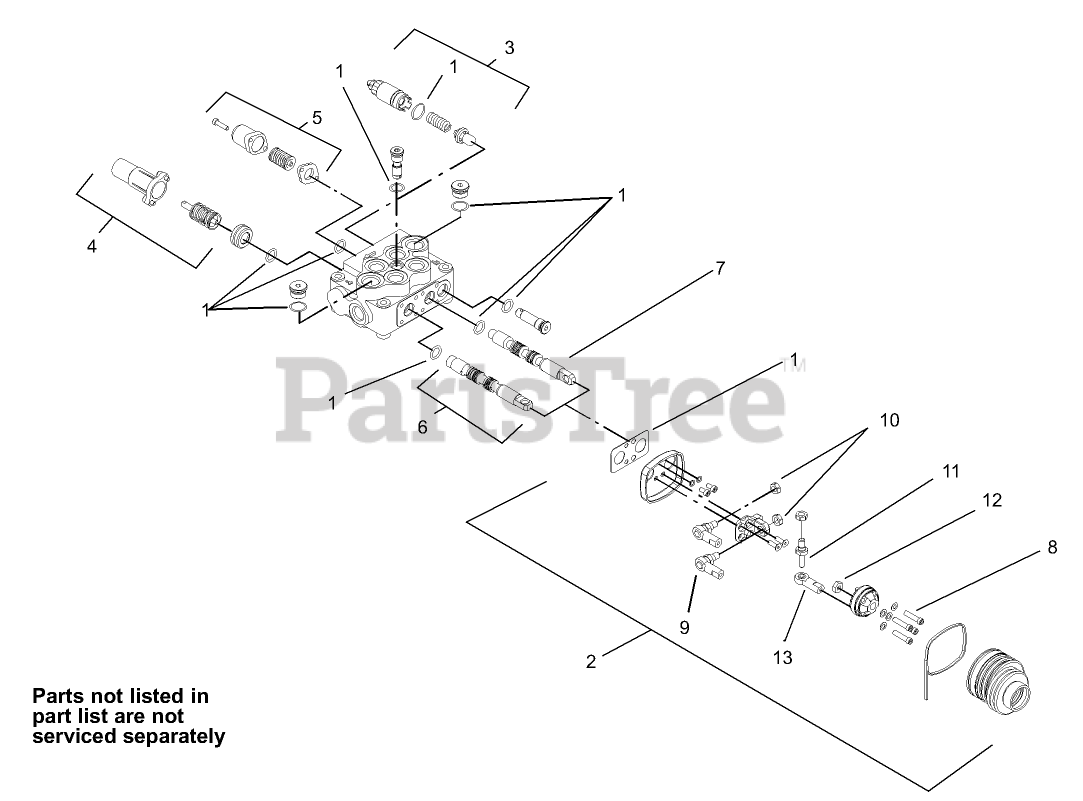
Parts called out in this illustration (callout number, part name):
1	SEAL KIT
2	JOYSTICK KIT
3	VALVE-RELIEF
4	Kit-Spring, Valve
5	Kit-Spring
8	Screw-Joystick
9	Joint-Articulated
10	Nut-Joystick
11	Pin-Joystick
12	NUT-GALVANISED
13	End-Rod
